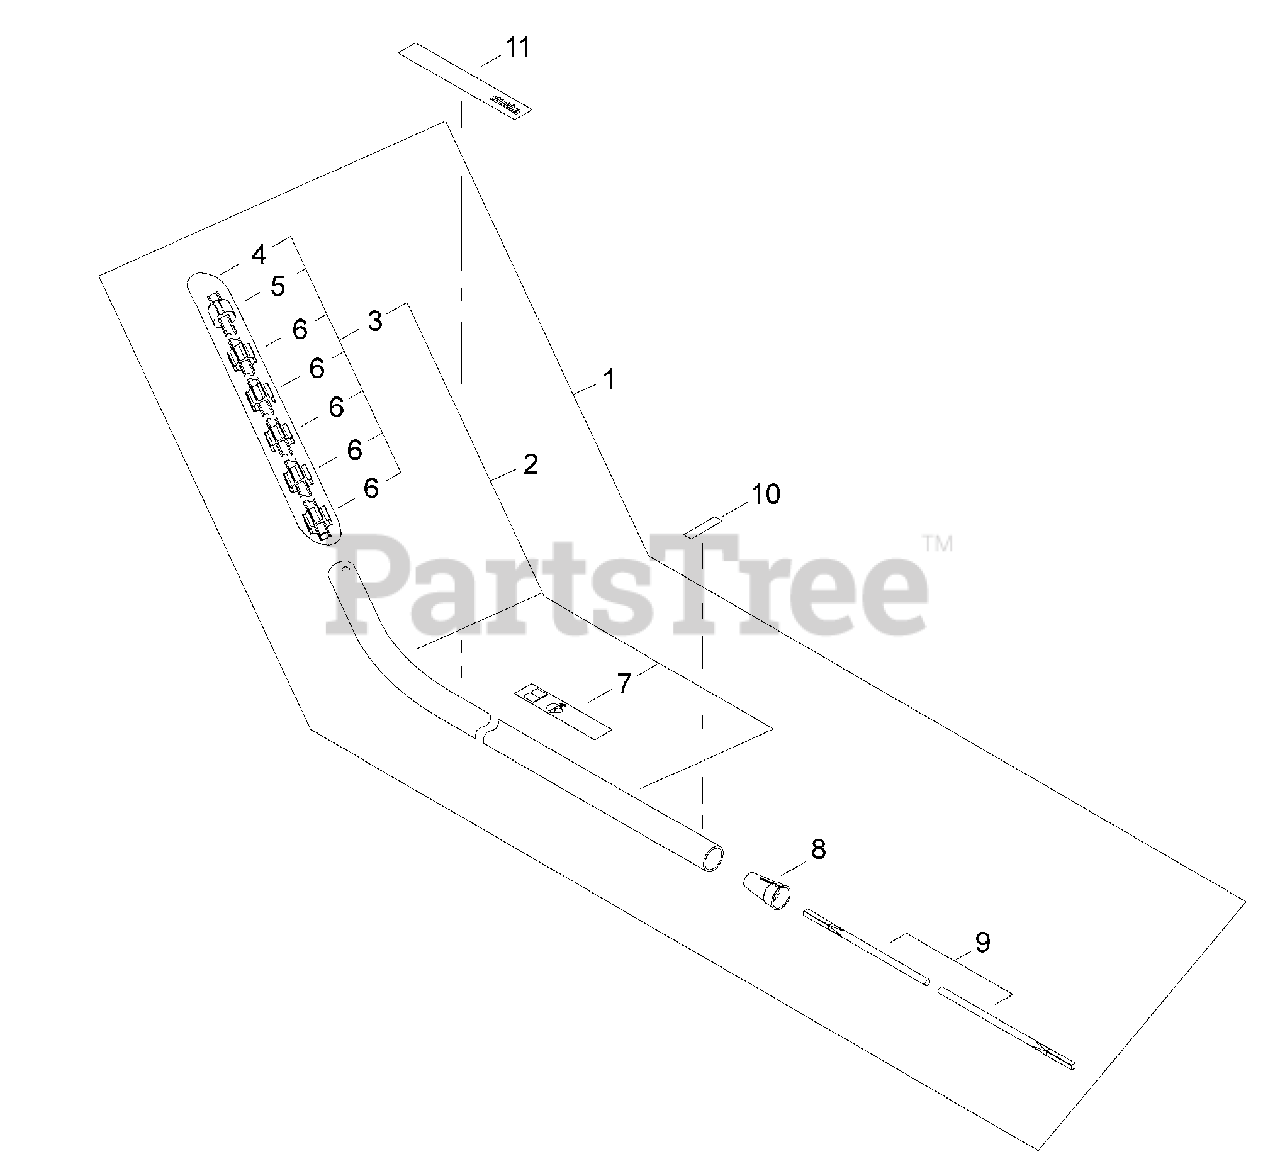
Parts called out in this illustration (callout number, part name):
1	MAIN PIPE ASSY
2	MAIN PIPE ASSY
3	LINER ASSY
4	LINER - FLEXIBLE
6	BUSHING
7	LABEL - CAUTION
8	SPACER
9	DRIVESHAFT - FLEXIBLE
10	LABEL - INSTRUCTION
11	LABEL - TRADE
